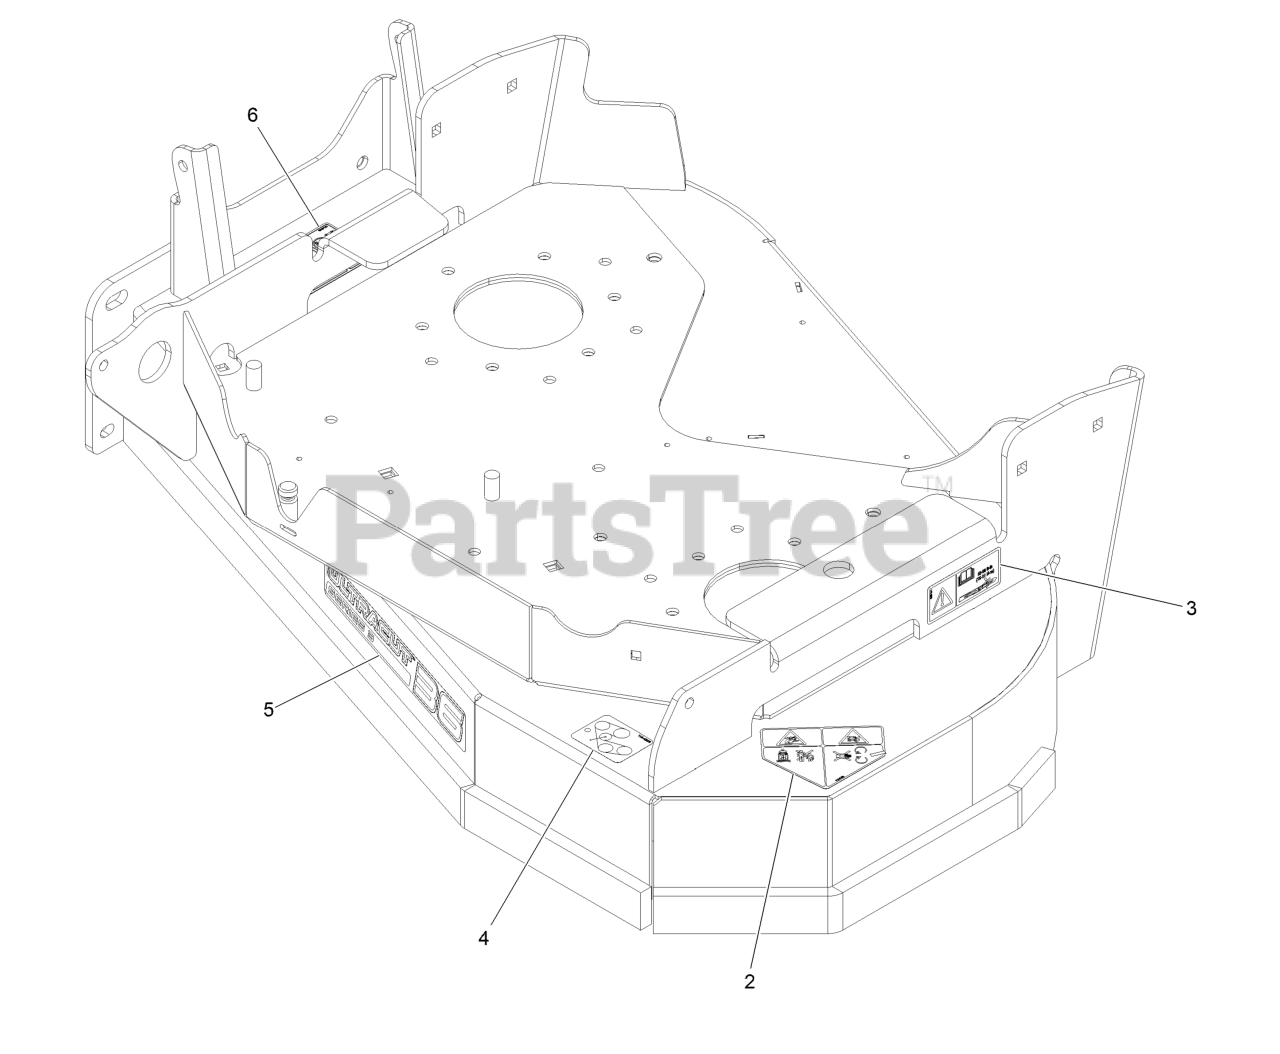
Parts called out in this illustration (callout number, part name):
2	Decal-Danger
3	Decal-Bolt Torque
4	Decal-Belt Routing 36
5	Decal-Ultracut 36 Series 3
6	Decal-Danger
